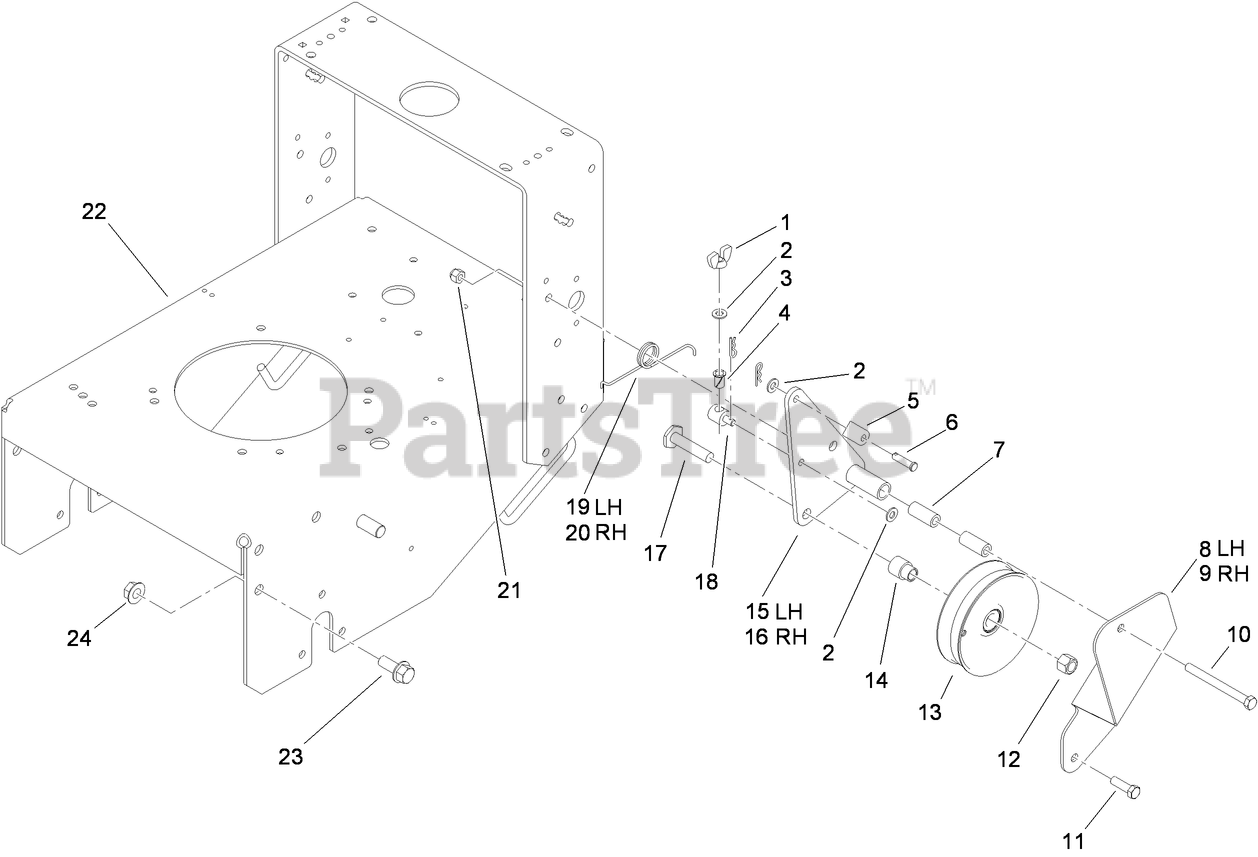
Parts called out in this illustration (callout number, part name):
1	NUT-WING
2	WASHER-PLAIN
3	PIN-COTTER
4	BUSHING-NYLON
5	FITTING-ROD
6	PIN-CLEVIS
7	SPACER-PIVOT, IDLER
8	SUPPORT-IDLER, LH
9	SUPPORT-IDLER, RH
10	SCREW-HH
11	SCREW-HH
12	NUT-LOCK, NI
13	PULLEY-IDLER
14	SPACER-PULLEY
15	ARM-IDLER, LH
16	ARM-IDLER, RH
17	SCREW-LEVELER
18	FITTING-ROD
19	SPRING-TORSION, LH
20	SPRING-TORSION, RH
21	NUT-LOCK, NI
22	FRAME-GEAR
23	SCREW-HHF
24	NUT-HF
